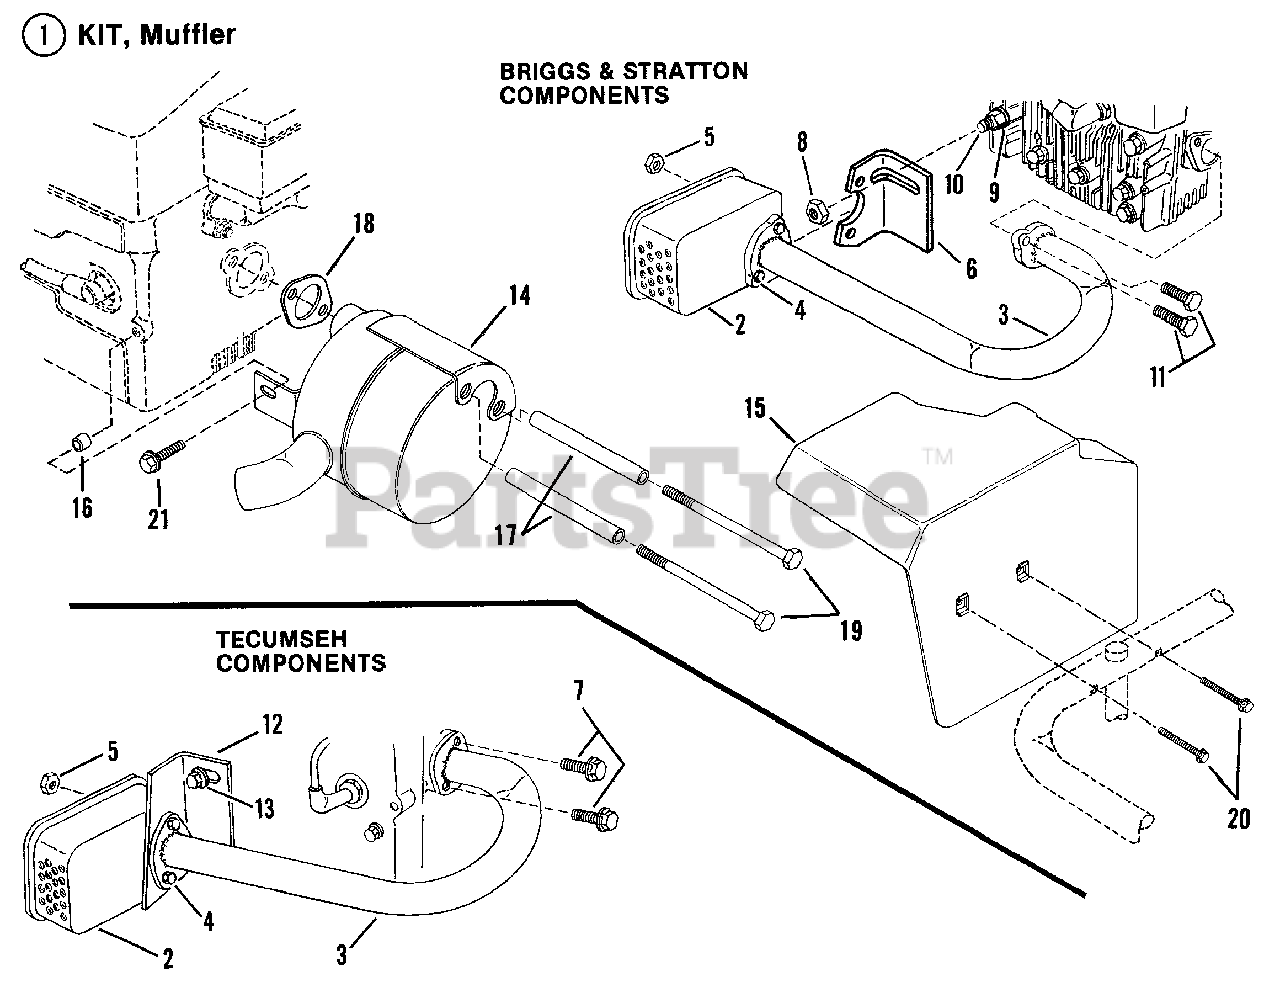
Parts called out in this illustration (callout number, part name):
1	KIT, Muffler
2	MUFFLER
3	TUBE, Exhaust
4	CAPSCREW, 5/16Cx3", Hex Head
5	LOCKNUT, 5/16-18 Hex Flange
6	MOUNTING
7	SCREW, 5/16-18x3/4" Hex Flange
8	NUT, 5/16-18 Hex
9	WASHER, Flat
10	STUD, Cylinder Head
11	CAPSCREW, 1/4-20x5/8" Hex Head
12	CLIP, Mounting
13	SCREW, 1/4Cx5/8" Self-Tapping
14	MUFFLER
15	ASSEMBLY, Heat Shield
16	SPACER
17	SPACER, Split
18	GASKET, Exhaust
19	SCREW, 5/16-18x4-1/4" Hex Cap
20	SCREW, #10-32x1-1/2" Hex Machine
21	BOLT, 1/4-20x1" Hex Flange Lock
